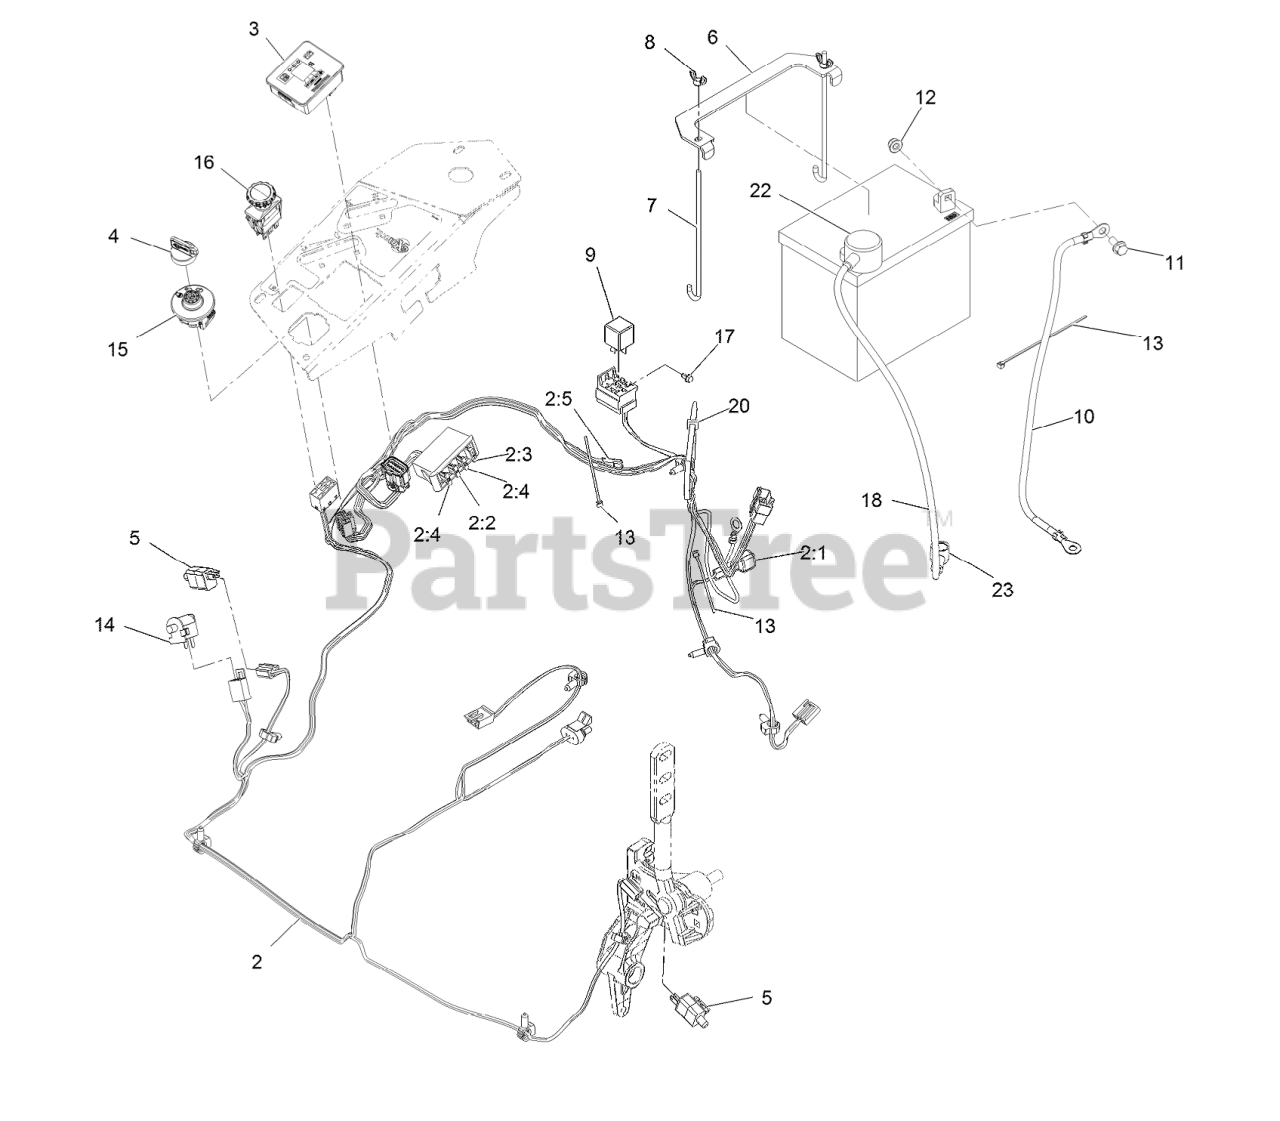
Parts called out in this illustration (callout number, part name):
2	HARNESS-WIRE, MAIN
2:2	FUSE-BLADE, 10 AMP
2:3	FUSE-BLADE, 15 AMP
2:4	FUSE-BLADE, 25 AMP
2:5	CAP-PLUG
3	FUEL/HOUR METER ASM
4	KEYS-IGNITION (SPARE PAIR
4	KEY-IGNITION
6	STRAP-TIE DOWN, BATTERY
7	BOLT-HOLDDOWN
8	WINGNUT
10	CABLE-BATTERY, NEGATIVE
11	SCREW-HHF
12	NUT-HF, NI
13	TIE-CABLE
14	SWITCH-BAIL
16	SWITCH-PTO, 10 AMP
17	SCREW-HWH
18	CABLE-BATTERY, POSITIVE
19	WASHER-FLAT
20	TIE-PLASTIC
22	INSULATOR-BATTERY
23	INSULATOR-SOLENOID
24	VALVE-PURGE
